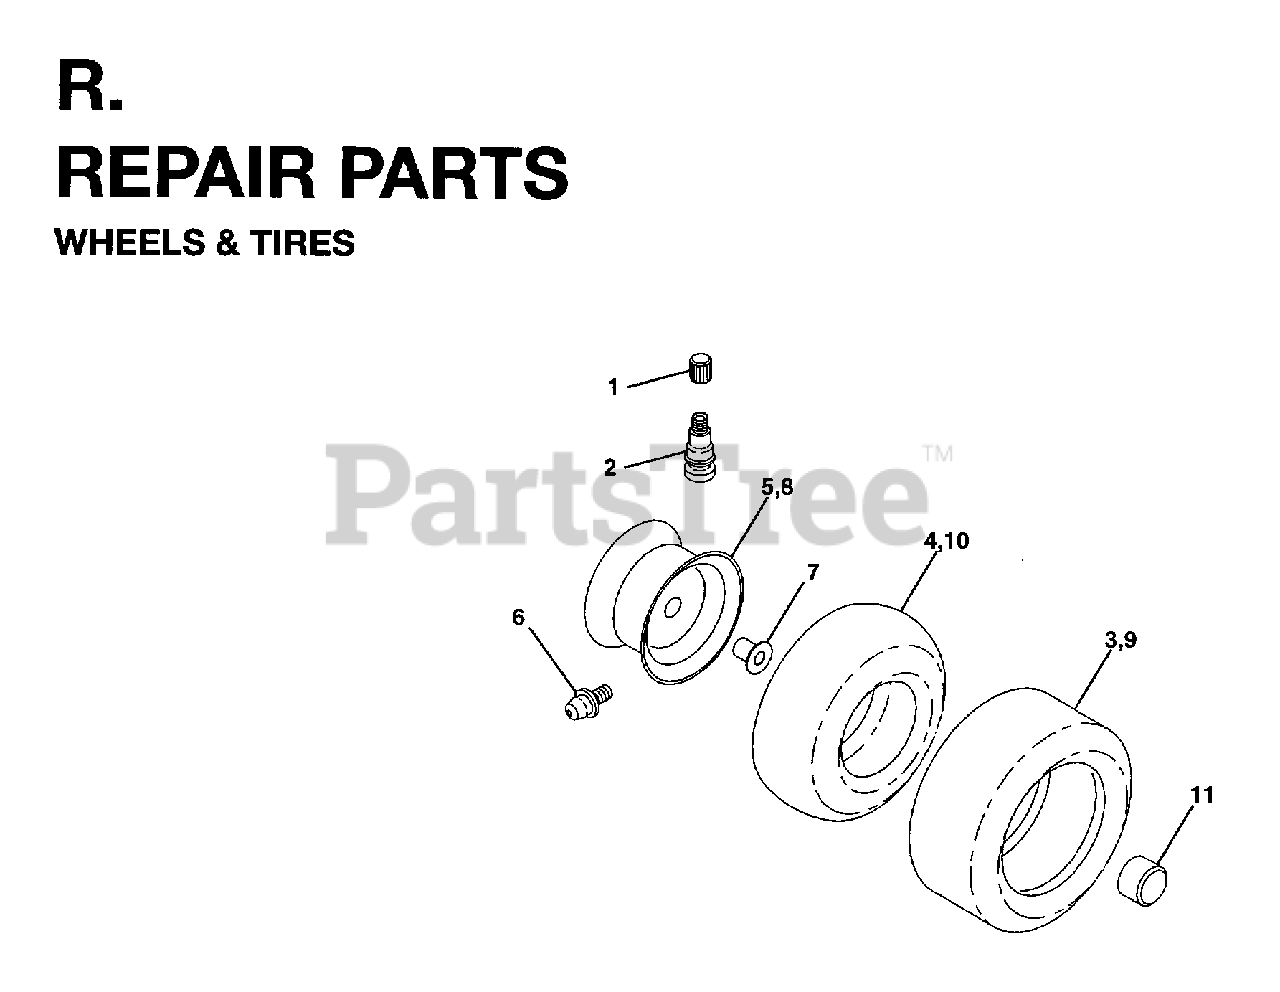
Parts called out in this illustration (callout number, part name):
1	VALVE CAP
2	VALVE STEM LT
3	TIRE
4	TUBE.5.3/4.5/6
5	RIM ASM 6" FRONT SILVER
6	FITTING LT
7	BEARING T
8	RIM 8" SILVER
10	TUBE - UNIVERSAL FOR 8" RIM
11	CAP-HUB FRONT LT
